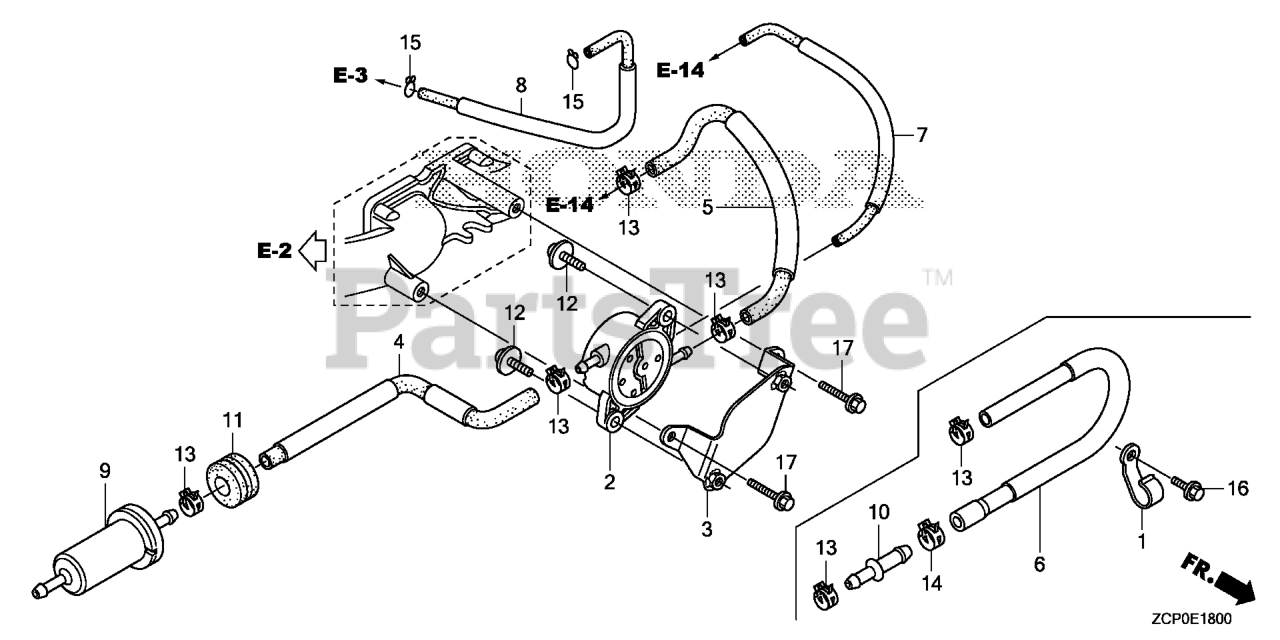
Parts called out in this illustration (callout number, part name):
2	PUMP ASSY., FUEL (MSDS)
3	STAY, FUEL PUMP
4	TUBE, COMP A FUEL
5	TUBE, COMP B FUEL
7	TUBE, PURGE
8	TUBE, DIAPHRAGM
9	STRAINER, FUEL
11	RUBBER, RR. FENDER
12	SCREW-WASHER (6X16)
13	CLAMP, TUBE (D10)
15	CLIP, TUBE (C11)
17	BOLT, FLANGE (6X14)
